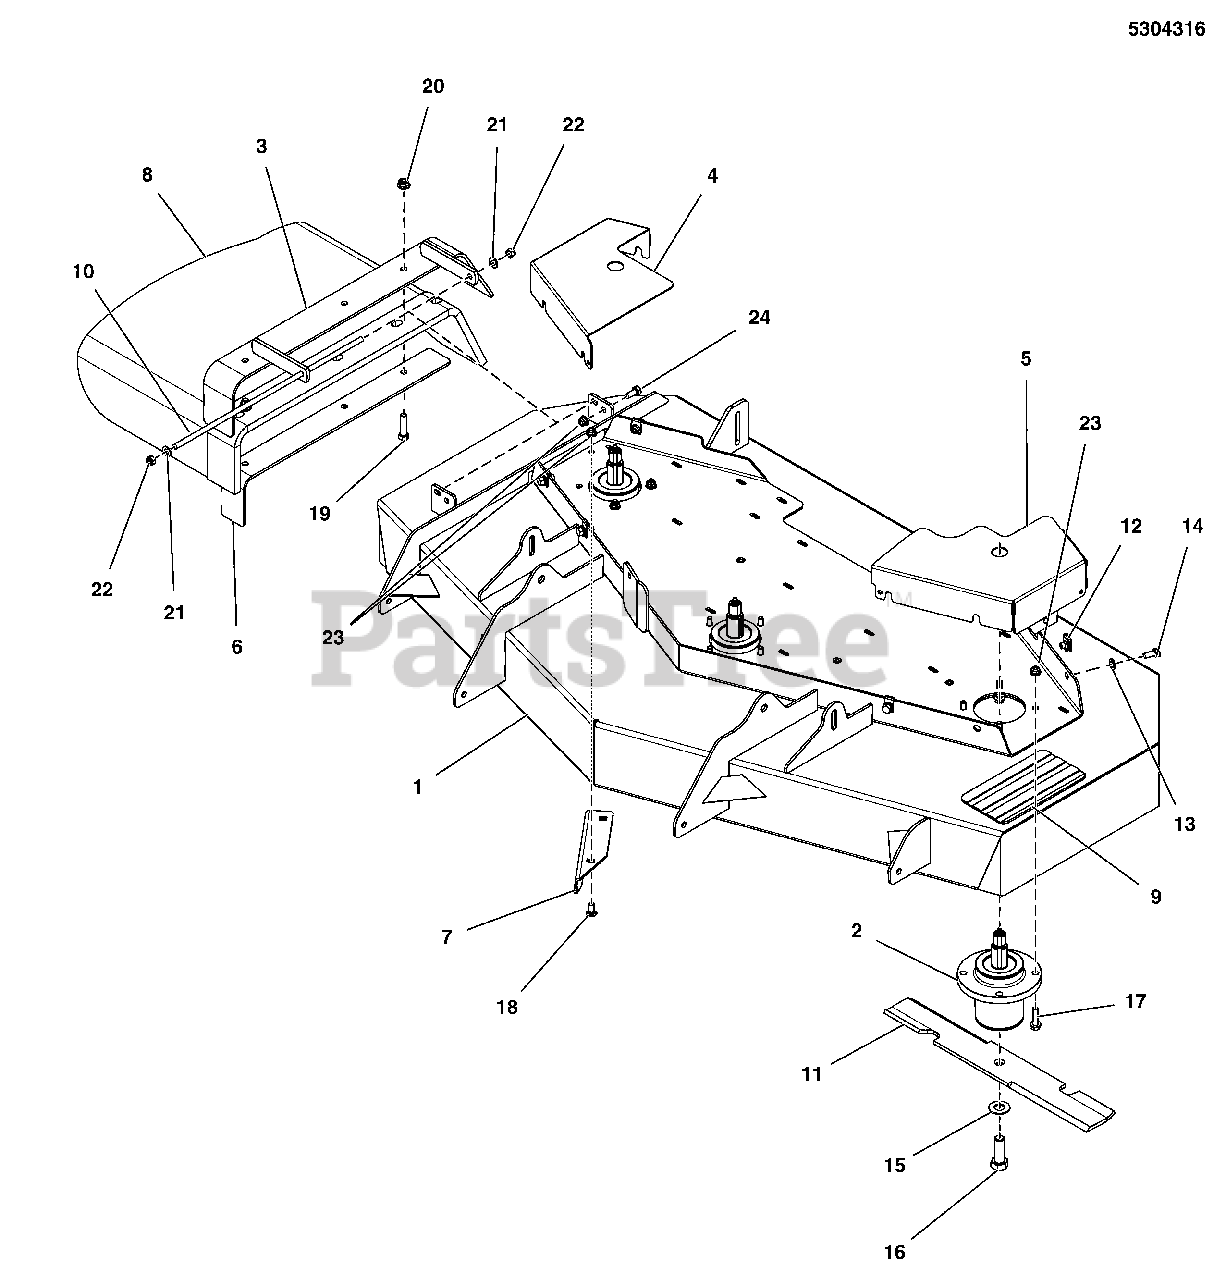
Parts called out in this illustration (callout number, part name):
1	DECK SHELL W/DECALS,52,CNTDR,5414522C
2	ASSM, SPINDLE, LOW PROFILE
3	WELD, MOUNT, DISCHARGE CHUTE - BLK
4	GUARD, 52 DECK, RH - RED
5	GUARD, 52 DECK, LH - RED
6	SUPPORT, DISCHARGE CHUTE - BLK
8	CHUTE, RUBBER DISCHARGE (5104442)
9	SAFETY WALK, 4.00 X 7.50
10	ROD, MOUNT, CHUTE 61, CZ
11	BLADE, 18", SET OF THREE (3)(SV)
12	BODY CLIP, 5/16-18-7GA MATERIAL
13	WASHER, 5/16 SAE
14	BOLT, 5/16-18 X 3/4 GD5
15	WASHER, BLADE BOLT, 9/16" F436, CZ
16	BOLT, 5/8-11 X 1-3/4 GD8
17	BOLT, 5/16-18 X 1 1/4 FLANGE
18	BOLT, 5/16-18 X 3/4, CARRIAGE
19	BOLT, 3/8-16 X 1-1/2, CARRIAGE, GD5, CZ
20	NUT, 3/8-16 HEX NYLOCK FLANGE
21	WASHER, 5/16 SAE
22	NUT, 5/16-24 HEX NYLON LOCK
23	NUT, 5/16-18 HEX NYLOCK FLANGE
24	SCREW, 5/16-18
